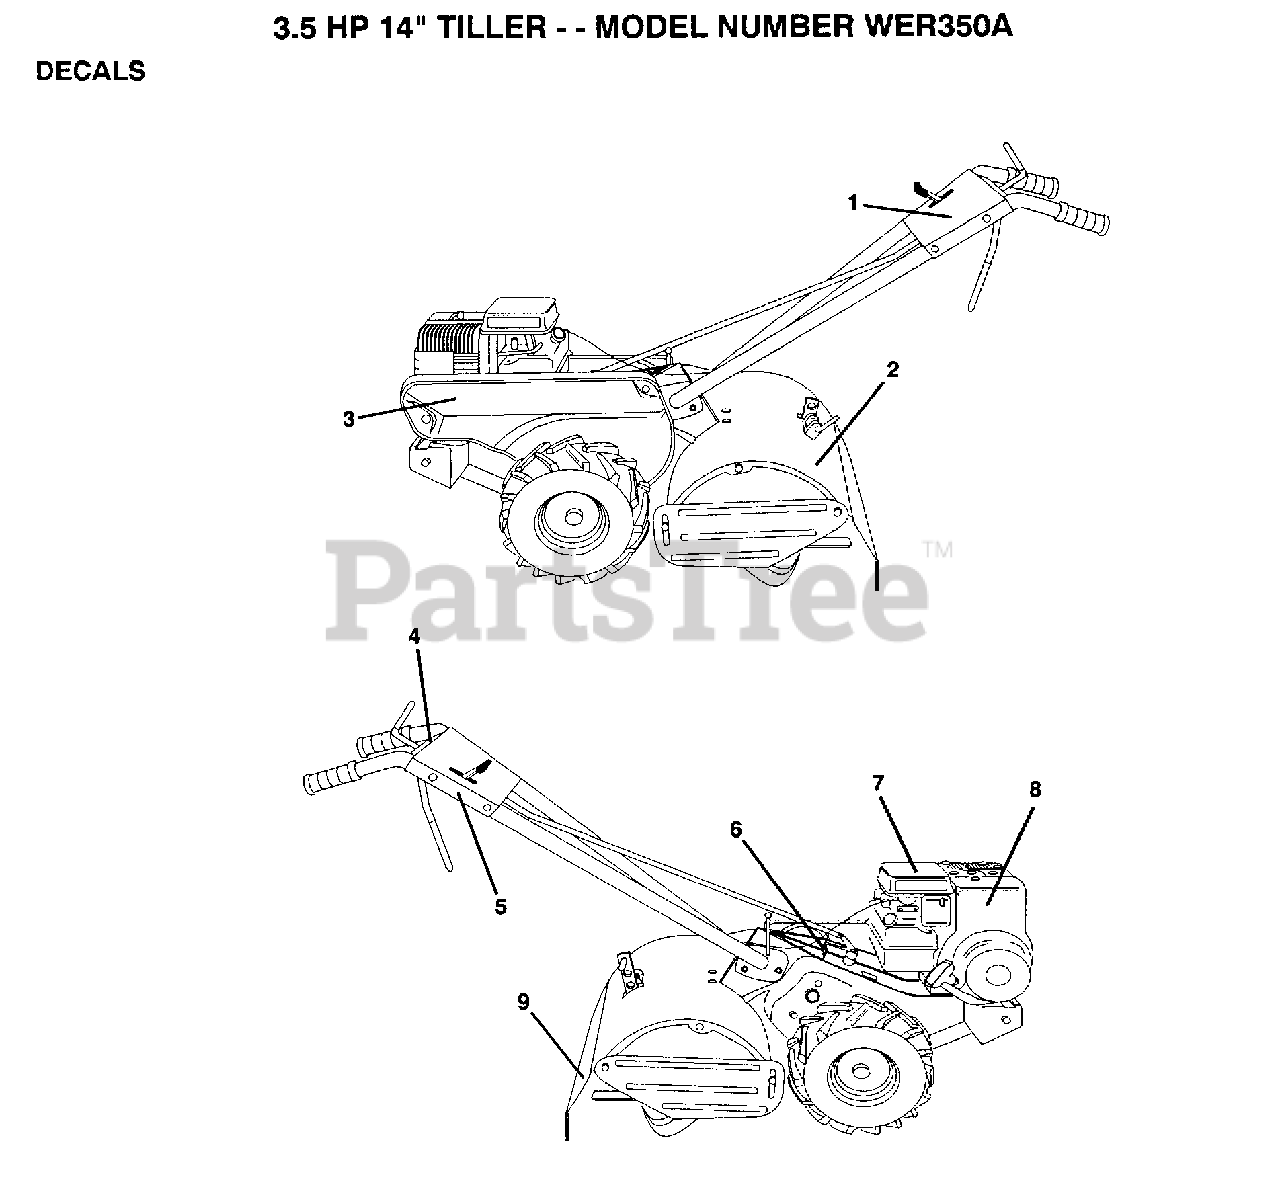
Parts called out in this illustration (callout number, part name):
1	DECAL.PNL.CNTL.
2	DECAL.SHLD.TINE
3	DECAL BELT GUARD
5	DECAL TI
7	DECAL TI
8	"DECAL,ENG HP"
